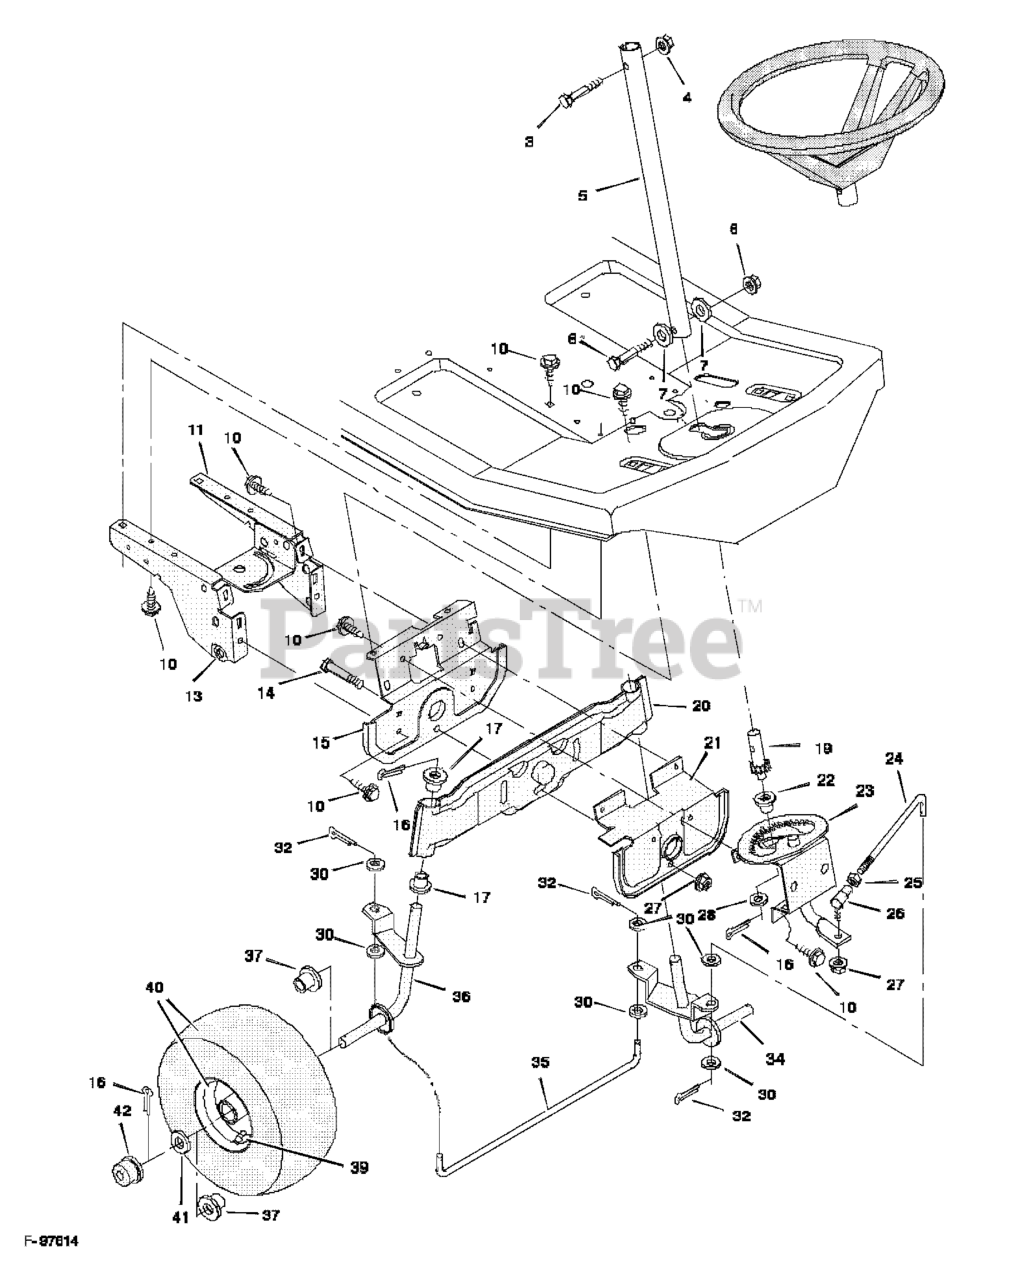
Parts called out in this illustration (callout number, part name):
1	Steering Wheel
3	Bolt, Hex
4	Locknut, Flange
5	Post, Steering
6	Nut, Hex
7	Washer
11	Plate, Left Suspension
13	Plate, Right Suspension
14	Bolt, Hex
15	Support, Front Axle
16	Pin, Cotter
17	Bearing, Spindle
19	Gear, Pinion
20	Axle Assembly, Front
21	Hanger Assembly, Front Axle
22	Bearing
23	Sector Assembly
24	Rod, Drag Link
25	Ball Joint, Steering
26	Nut, Hex
27	Locknut, Flange
28	Washer
30	Washer
32	Pin, Cotter
34	Spindle Assembly, Left
35	Rod, Tie
36	Spindle Assembly, Right
37	Bearing, Wheel
39	Valve Stem
40	Wheel & Tire Assembly
42	Cap, Hub
